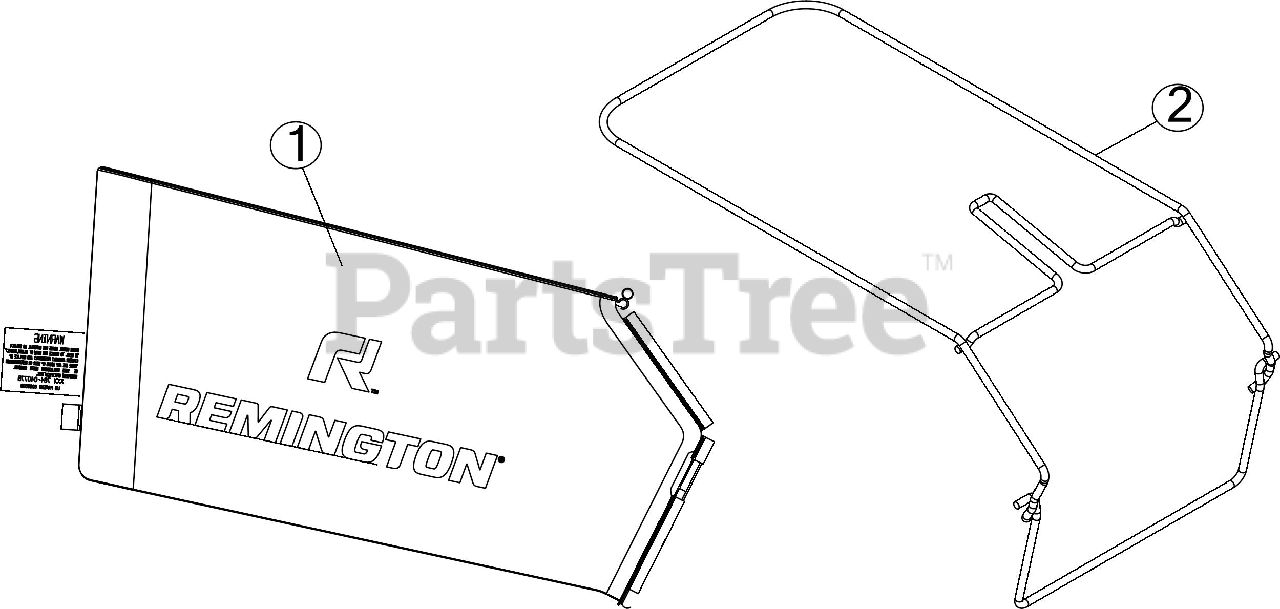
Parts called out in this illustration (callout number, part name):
1	GRASSBAG-21"
1	GRASSBAG ASSEMBLY
2	GRASSBAG FRAME ASSEMBLY
